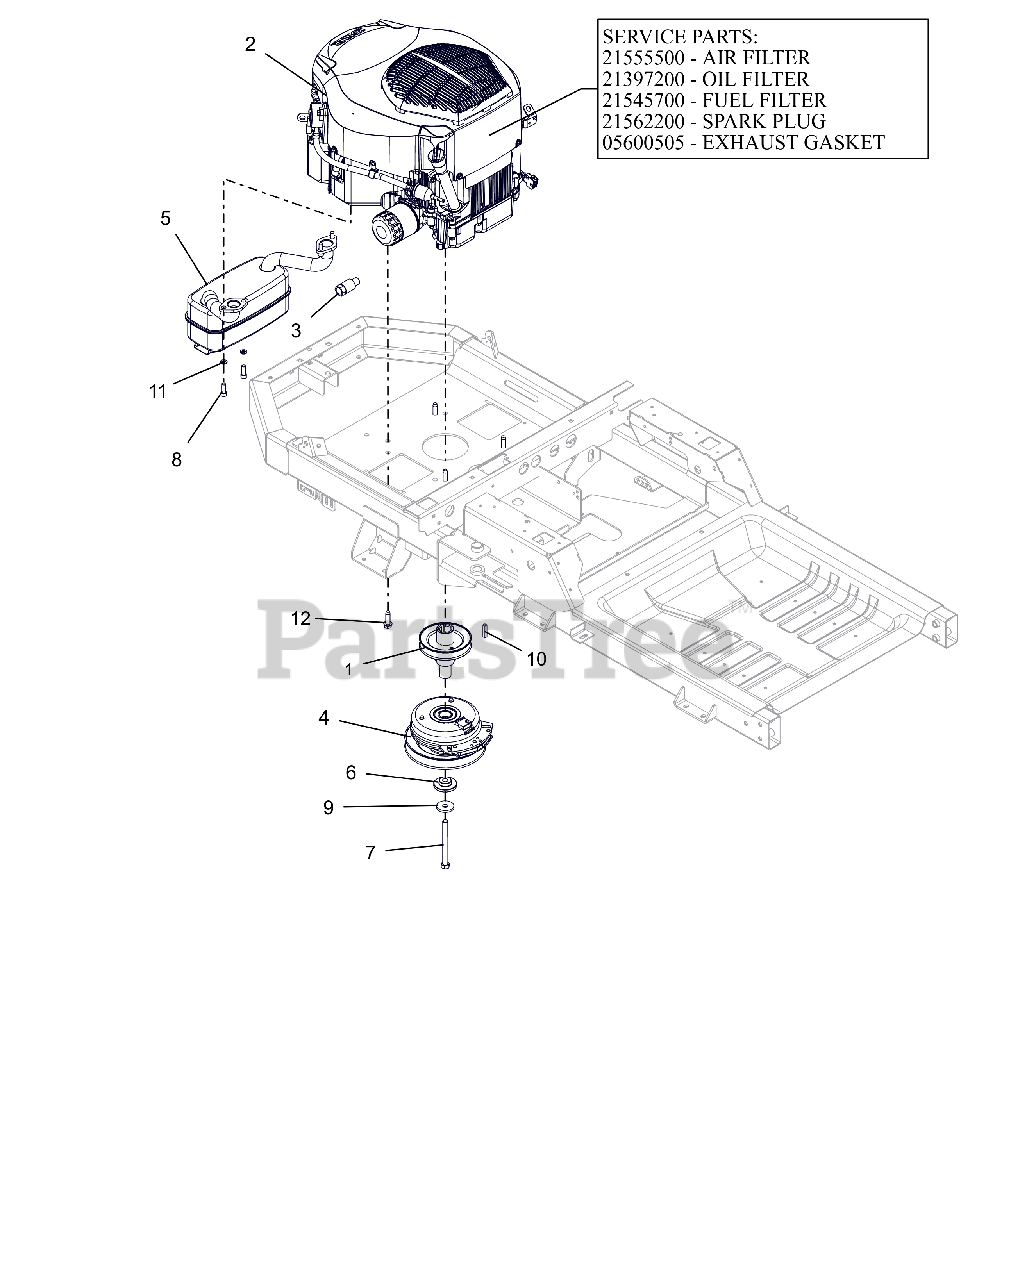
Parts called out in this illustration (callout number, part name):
1	WLDMT, DRIVE SHEAVE-X
2	ENGINE, KOHLER 24HP TWIN
2	AIR CLEANER, KOHLER
2	FILTER, OIL - KOH CV20
2	FILTER-FUEL KOHLER COURAGE PRO
2	PLUG, SPARK (RFI)
2	GASKET, MUFFLER COURAGE TWIN
3	DRAIN, OIL
4	CLUTCH,105FTLB MONOPOLE 6.83"
5	MUFFLER - KOHLER
6	BSHG-FLG .469X1.06X.574X2.0
7	BLT, HEX .44-20X4.50 G8 ZCC NT
8	SCR-CAP .31-18X.88 S/HD G8 ZCC
9	WASHER, 7/16" SPRING DISK
10	KEY-SQ .25 X 1.25 X .25 SAE
11	WSHR,LK-REG .312X.078 ZCC
12	SCR,TAP .375-16X1.25HWH TR ZCC
